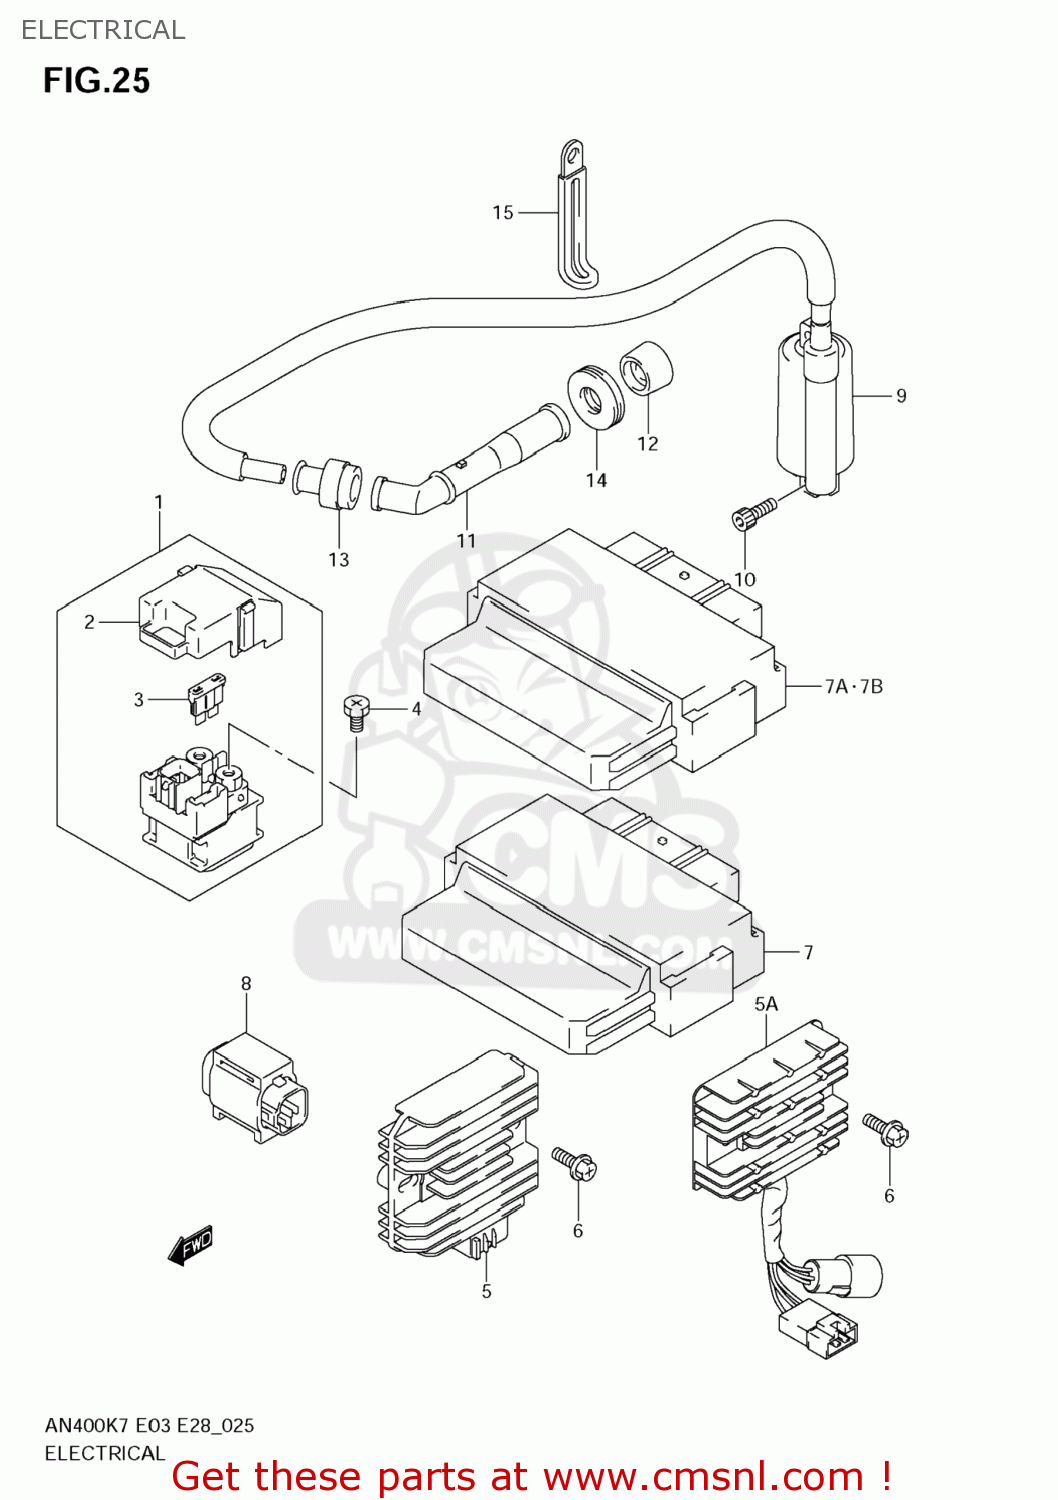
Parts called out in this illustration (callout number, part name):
1	RELAY ASSY,STARTING MOTOR
2	COVER
3	FUSE(30A)
4	SCREW(6X8)
5	RECTIFIER ASSY
5A	RECTIFIER ASSY
6	SCREW
7	CONTROL UNIT,FI
7A	CONTROL UNIT,FI
7B	CONTROL UNIT,FI
8	SENSOR ASSY,FUEL CUT
9	COIL ASSY,IGNITION
10	BOLT
11	CAP,SPARK PLUG
12	SEAL,SPARK PLUG
13	SEAL,HIGH TENSION CORD
14	COVER,SPARK PLUG CAP
15	CLAMP(L:45)
